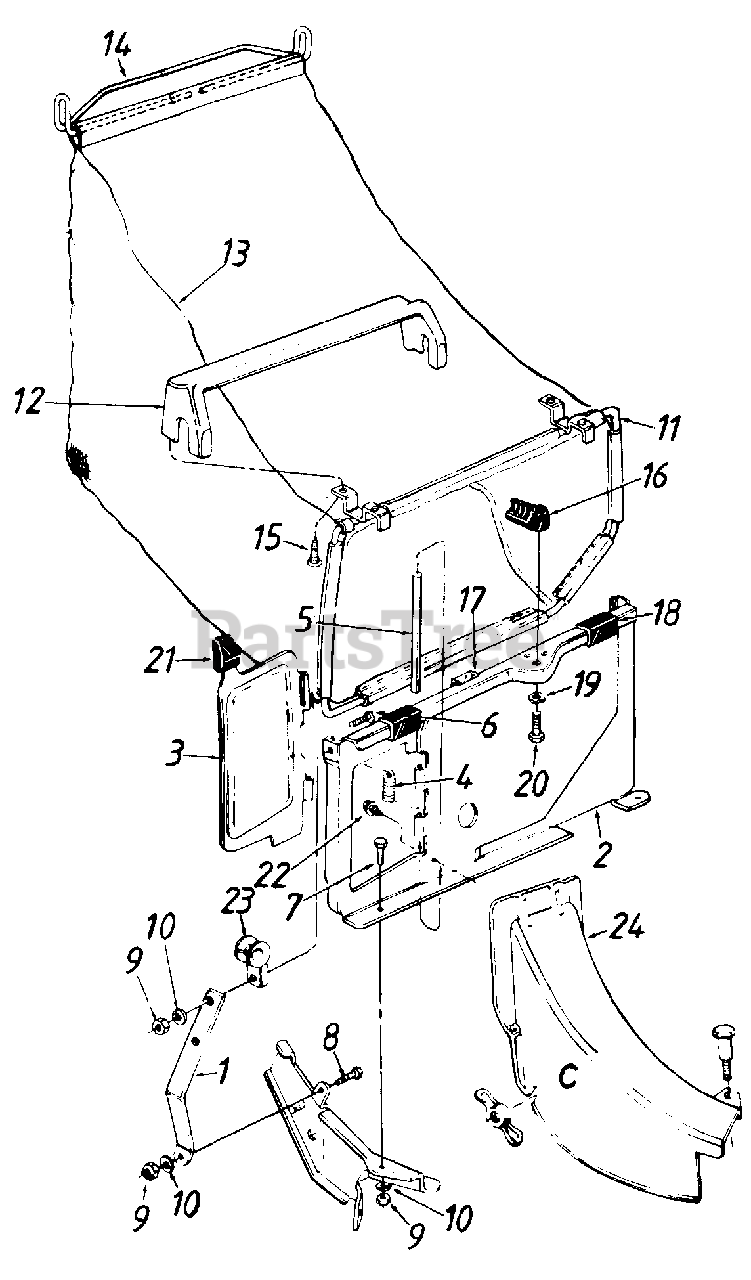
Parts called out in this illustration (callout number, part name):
1	Panel Support Brkt.
2	Top Catcher Panel Ass'y.
3	Top Discharge Door
4	Torsion Spring
5	Pivot Pin
6	Truss Mach. Scr. 1/4-20 x .75" Lg.
7	Hex Bolt 1/4-20 x .50" Lg.
8	Hex Bolt 1/4-20 x .62" Lg.
9	Hex Nut 1/4-20 Thd.
10	L-Wash. 1/4" I.D.
11	Front Grass Catcher Frame
12	Grass Catcher Handle
13	Grass Bag
14	Upper Bag Handle
15	Hex AB-Tap Scr. #12 x 1.0"
16	Grass Catcher Locking Knob
17	Foam Strip 1" Lg.
18	Panel Clip
19	Spring Wash. .32" I.D.
20	Hex Bolt 1/4-20 x .62" Lg.
21	Door Grip
22	Hex B-Tap Scr. #10 x .381'
23	Rope Guide
24	Top Discharge Chute Ass'y.
